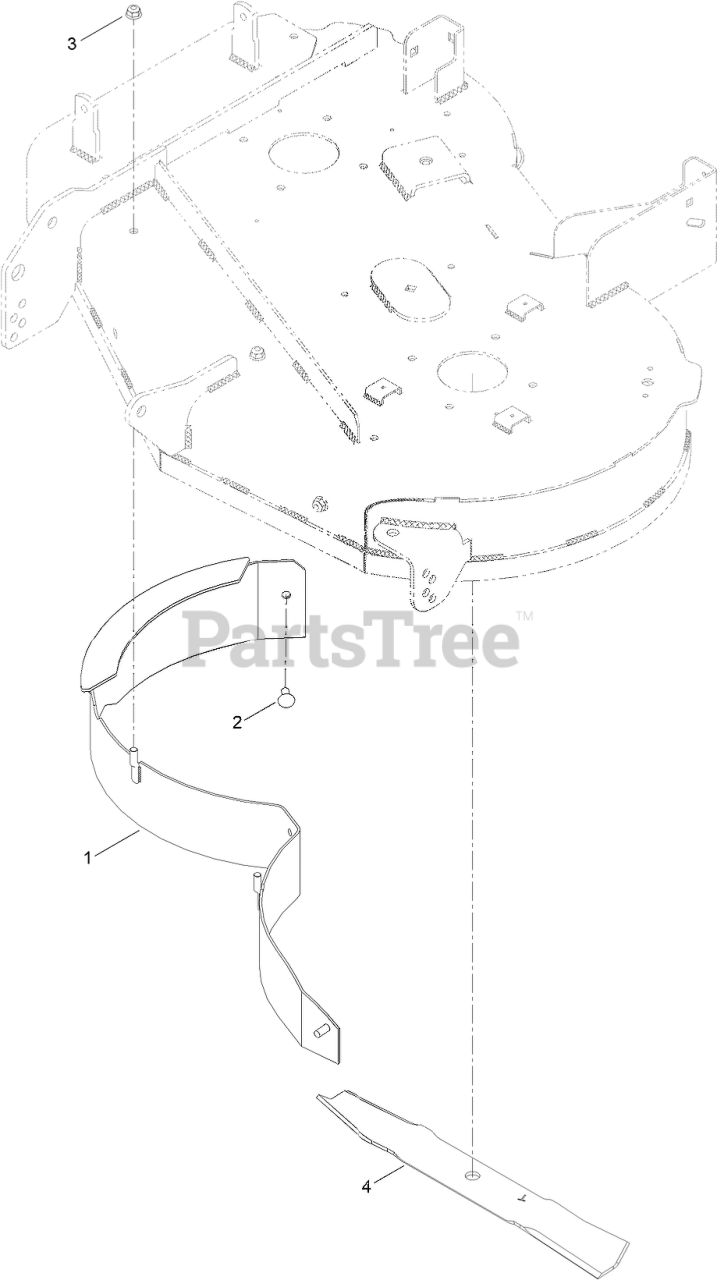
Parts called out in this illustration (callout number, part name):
1	BAFFLE ASM
2	BOLT-CARR
3	NUT-HF, NI
4	BLADE-MULCH, 17.50 INCH
